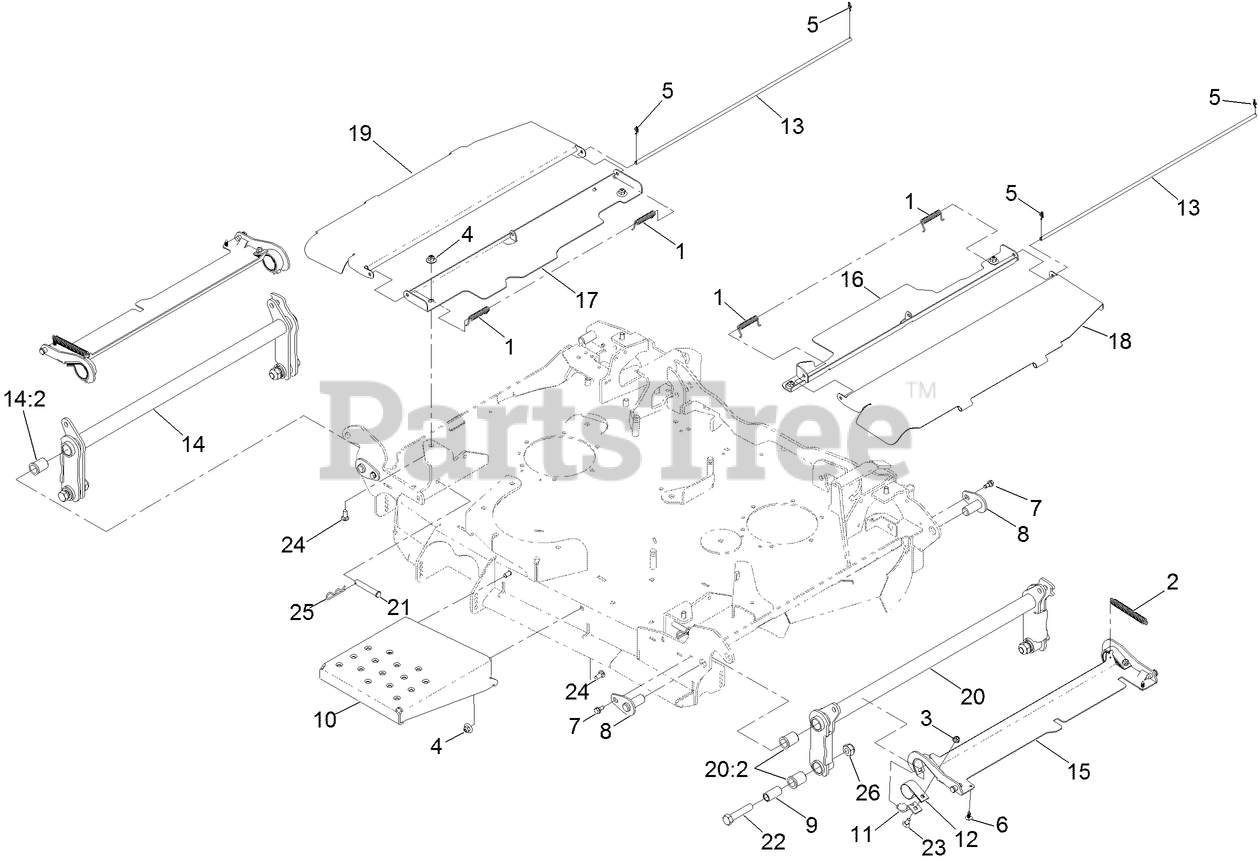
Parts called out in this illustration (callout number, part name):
1	SPRING-TORSION
2	SPRING
3	NUT-HF, NI
4	NUT-FLANGE, NI
5	PIN-COTTER, LOCKING
6	PLUG-PLASTIC
7	SCREW-SHOULDER
8	PIN-DECK
9	BUSHING-FLOAT, DECK
10	PANEL-STEP
11	PLATE-RETAINER, BEARING
12	BEARING-STRAP, NYLON
13	COVER-ROD, PIVOT
14	RH FOLD ARM ASM
14:2	BUSHING-FLANGED
15	COVER-WING
16	SHIELD-CENTER, LH
17	SHIELD-CENTER, RH
18	PANEL-SHIELD HINGE, LH
19	PANEL-SHIELD HINGE, RH
20	LH FOLD ARM ASM
20:2	BUSHING-FLANGED
21	PIN-CLEVIS
22	SCREW-HH
23	SCREW-CARR
24	BOLT-CARR
25	PIN-HAIR
26	NUT-LOCK
